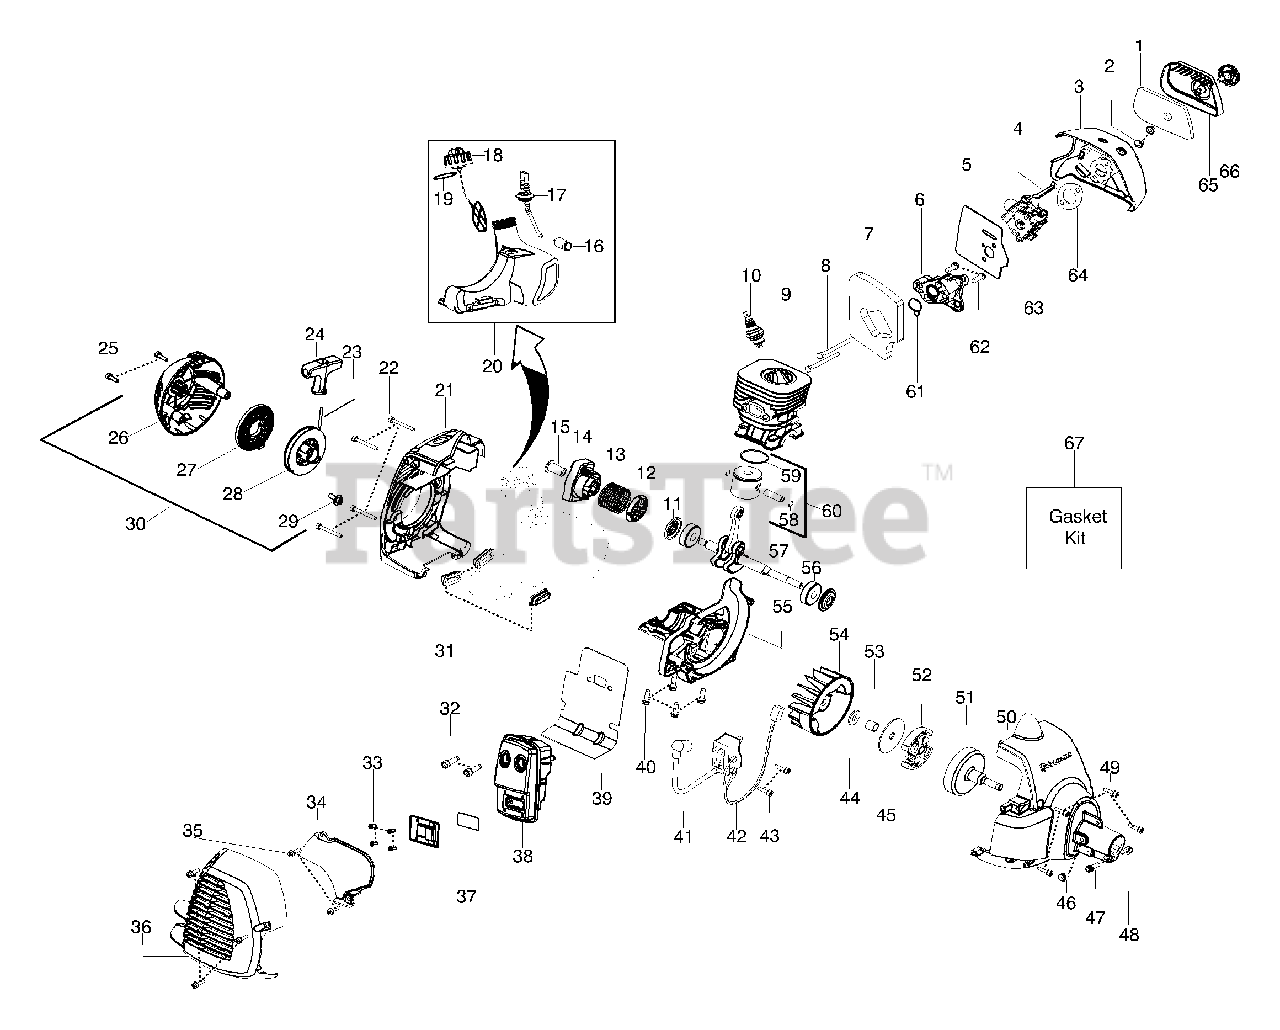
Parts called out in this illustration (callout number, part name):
2	Nut-Carb. Screw
3	Air Box
4	Lever - Choke
5	Kit-Carb. Gasket
6	Adaptor-Carb.
7	Kit-Gasket (foam)
9	Cylinder
10	Plug-Spark (RCJ-8Y)
11	Kit-Crankshaft seal
12	Washer-Starter
13	Spring-Starter Cup
14	Assy-Starter Cup
15	Coupling-Starter
16	Assy-Fuel Filter
17	Kit-Fuel Line
18	Assy-Cap w/ret.
19	O-ring - Fuel Cap
20	Assy-Fuel Tank
21	Shroud-Rear
24	Handle-Starter
26	Starter Hsg. w/eyelet
27	Kit-Starter Spring
28	Kit-Starter Pulley
30	Assy-Starter Hsg.
31	Isolator-Tank
32	Bolt-Muffler
34	Shield-Heat
36	Guard-Muffler
37	Kit-Spark Arrestor
38	Assy-Muffler
39	Gasket-Paper Metal
42	Assy-Leadwire
45	Washer-Clutch
50	Assy-Fan Housing
51	Assy-Clutch Drum
52	Kit-Clutch Assy.
55	Crankcase-Machined
57	Kit-Crankshaft
58	Retainer-Piston Pin
59	Ring-Piston
60	Kit-Piston
61	Kit-Gasket (adaptor seal)
63	Kit-Carb.
64	Kit-Gasket (air box)
65	Cover-Air Box
67	Kit-Gasket
